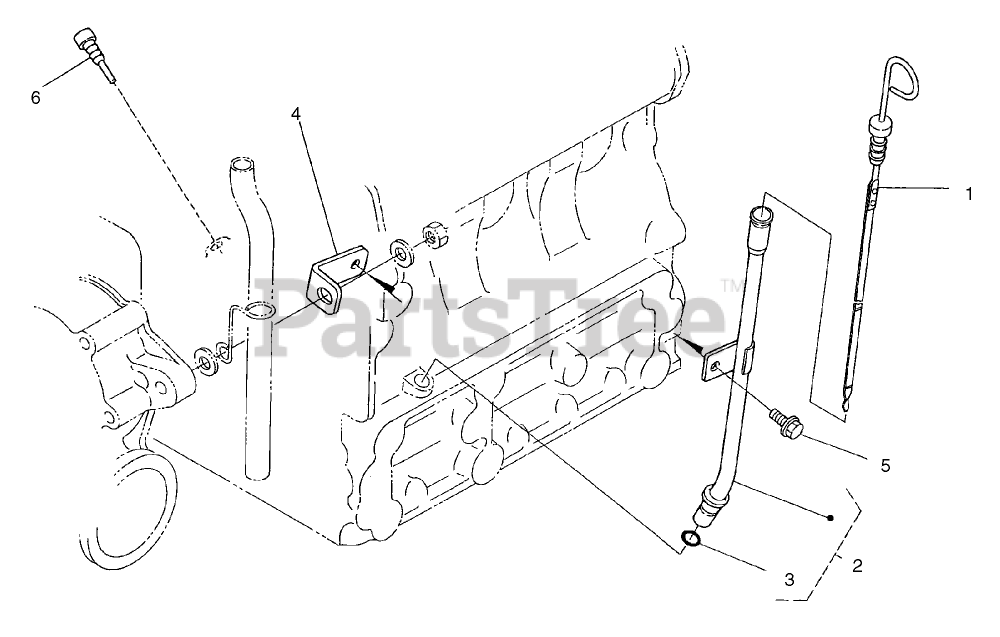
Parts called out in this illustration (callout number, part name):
1	GAUGE-OIL
2	OIL GAUGE GUIDE ASM
3	OBS O-RING
4	SUPPORT-GUIDE, GAUGE
5	BOLT-FLANGE
6	PLUG-RUBBER
